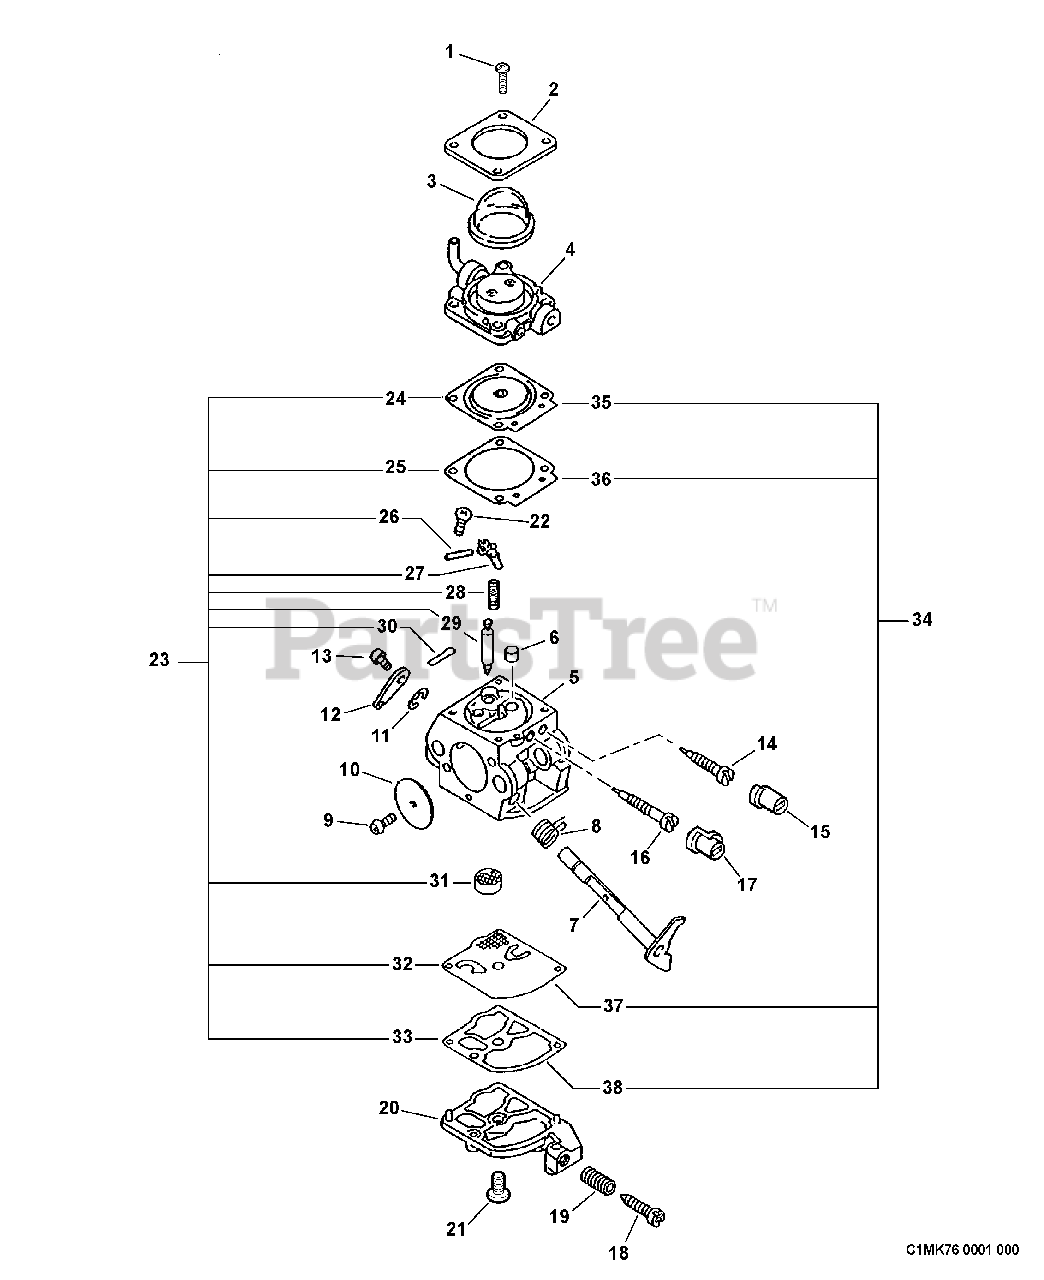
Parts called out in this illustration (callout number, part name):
2	RETAINER, PURGE BULB
3	BULB, PURGE
4	BODY ASSY, PURGE
5	BODY, CARBURETOR
6	NOZZLE, CHECK VALVE
7	SHAFT, THROTTLE
8	SPRING, THROTTLE RETURN
10	VALVE, THROTTLE
12	LEVER, THROTTLE
14	NEEDLE, HIGH SPEED
15	CAP, LIMITER - RED
16	NEEDLE, LOW SPEED
17	CAP, LIMITER - WHITE
19	SPRING, IDLE ADJUST
20	COVER, PUMP
23	REPAIR KIT
24	DIAPHRAGM, METERING
25	GASKET, METERING
26	PIN, METERING LEVER
27	LEVER, METERING
28	SPRING, METERING LEVER
29	VALVE, INLET NEEDLE
30	PLUG, WELCH
31	STRAINER
32	DIAPHRAGM, PUMP
33	GASKET, PUMP
34	GASKET / DIAPHRAGM KIT
35	DIAPHRAGM, METERING
36	GASKET, METERING
37	DIAPHRAGM, PUMP
38	GASKET, PUMP
